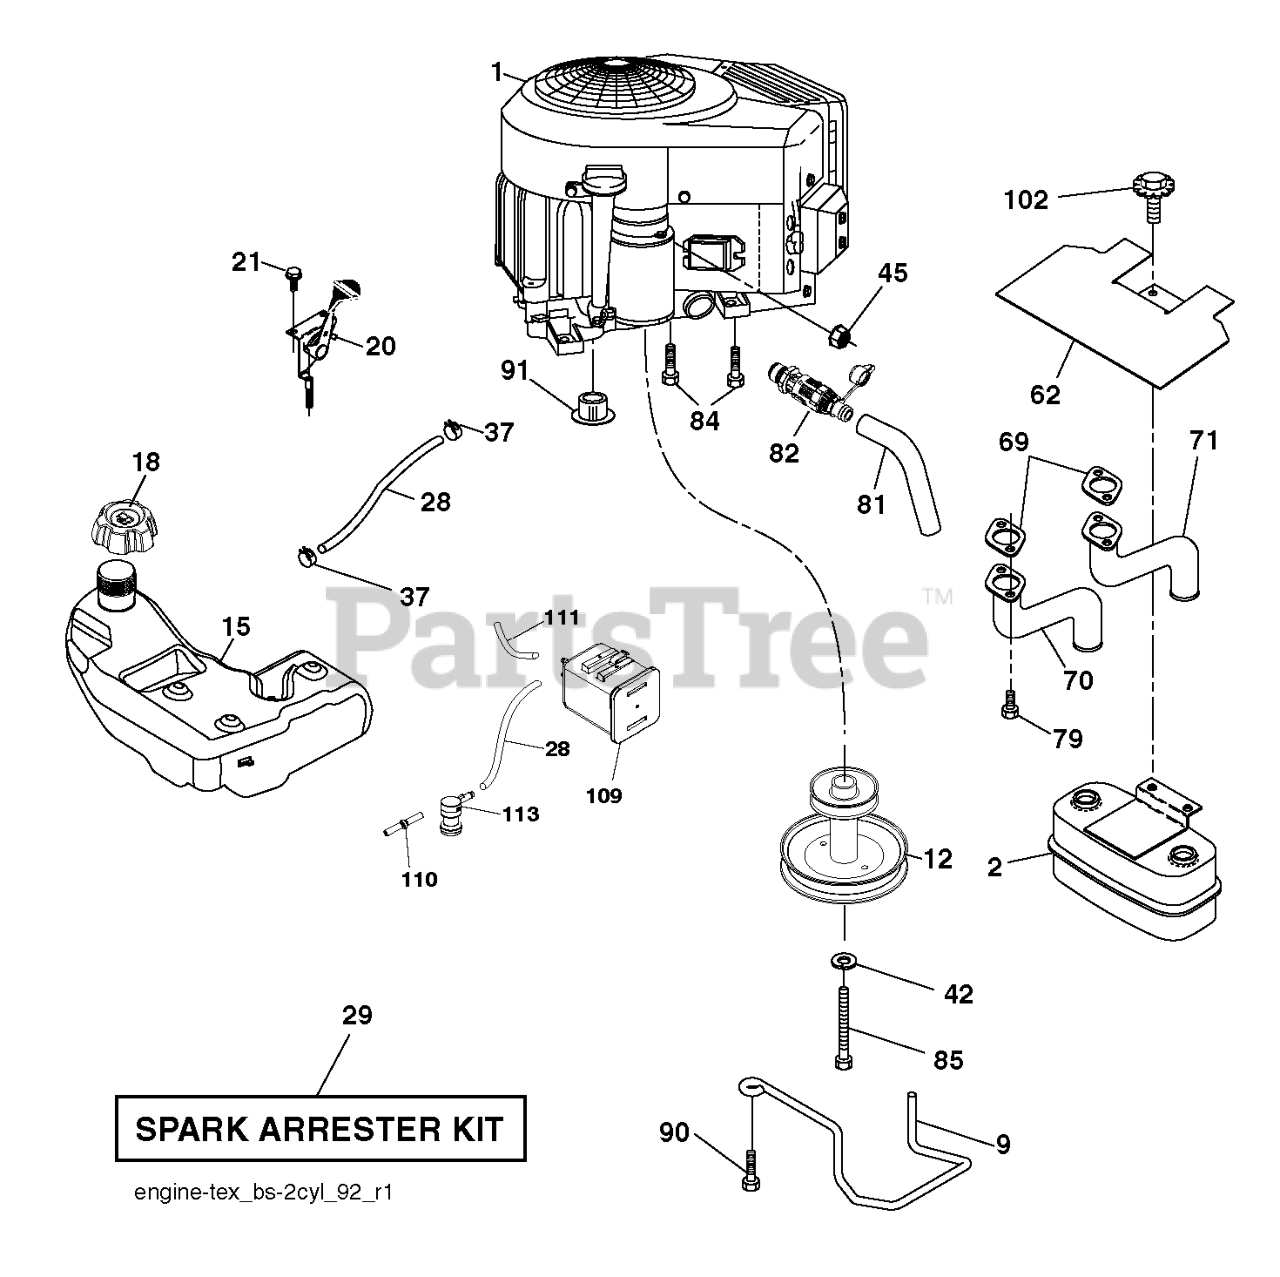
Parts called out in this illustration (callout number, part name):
2	MUFFLER.ASM.TWN.EXTNDED.DFLCTR
9	KEEPER BELT ENGINE
12	RP_PULLEY ENGINE
15	TANK.ASM.FUEL.3GA.CARB
18	CAP.ASM.FL.RITCH.3"E10.SYM.498
20	CONTROL.TH/CK.COBRA.B&S.TWN.BK
21	SCREW.#10 X 0.750.BOS
28	LINE.FUEL.64"REAR.EMIS
29	KIT.SPARK ARRESTOR 794945 B&S
37	HOSE CLAMP
42	LOCKWASHER
45	NUT
62	SHIELD.HEAT.MUFFLER
69	GASKET.MUFFLER
70	EXHAUST.TUBE.LH.BS/TWIN
71	EXHAUST.TUBE.RH.B&S.TWIN.INTEK
79	SCREW.SOCKET.HEAD.5/16-18
81	TUBE, DRAIN OIL ASM.
82	VALUE.OIL.DRAIN
84	SCREW.3/8-16
85	BOLT HEX 7/16-20X4-1/4"
87	BOLT 5/1618UNC X 3/4 W/ SEMS
90	SCREW 3/8-16X1
91	BUSHING.1.375OD
109	CANNISTER, CARBON
110	VALVE.ASM.ANTI-SLOSH
111	PURGE.LINE.36"REAR.CALIFORNIA
113	VALVE.SLANT.CARTRDG.90 DEG.TEX
